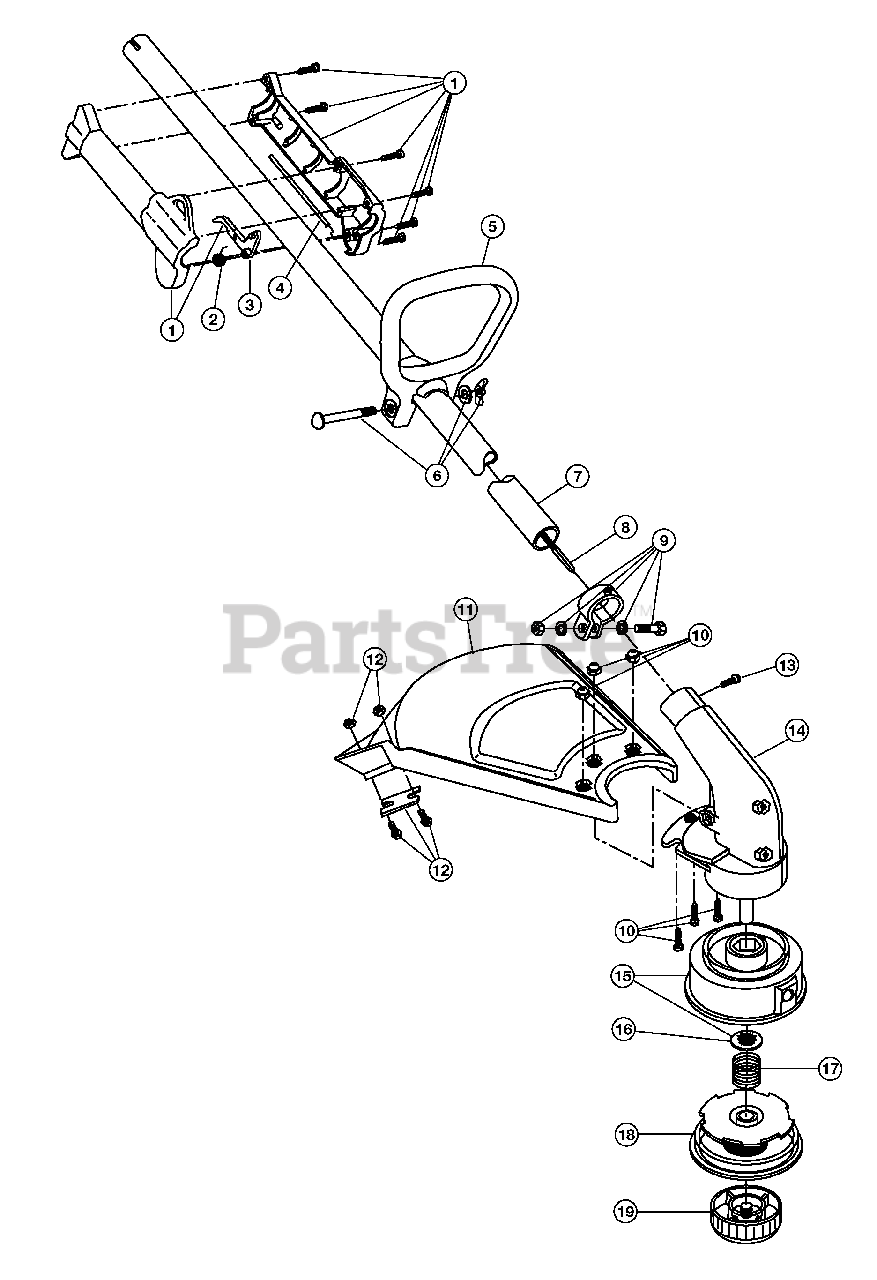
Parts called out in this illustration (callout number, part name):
1	Throttle Housing and Trigger Assembly
2	Throttle Trigger Spring
3	Throttle Trigger
4	Throttle Cable Housing Assembly
5	D-Handle
6	D-Handle Hardware Assembly
7	Drive Shaft Housing Assembly
8	Flexible Drive Shaft
9	Lower Clamp Assembly
10	Guard Mounting Screw Assembly
11	Guard and Blade Assembly
12	Blade Assembly
13	Anti-Rotation Screw
14	Gearbox Assembly
15	Outer Spool Assembly
16	Retainer
17	Spring
18	Inner Reel
19	Bump Head Knob Assembly
